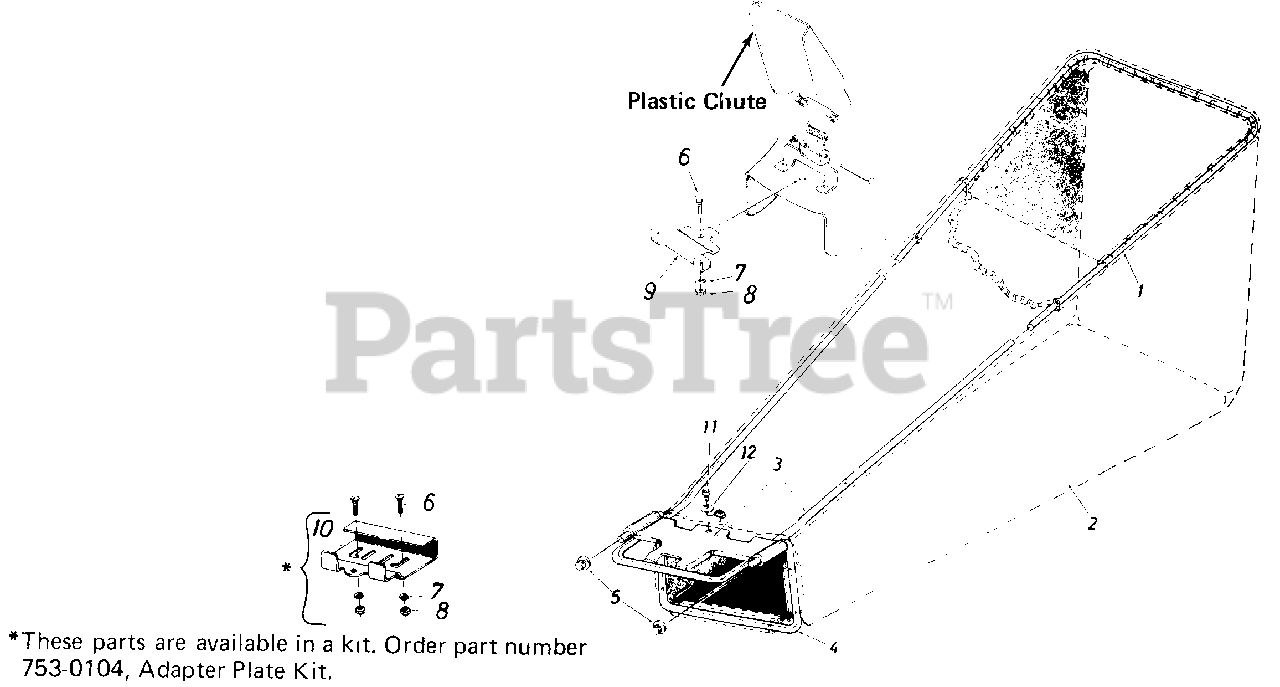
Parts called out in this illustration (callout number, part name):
1	Frame-Upper
2	Grass Catcher Bag
3	Frame-Lower
4	Lower Frame Rod
5	Push Cap
6	Carriage Bolt
7	LockWasher 1/4" I.D.*
8	Hex Nut 1/4-20 Thd.*
9	Adapter Plate
10	Adapter Plate
11	Self-Tap Scr. 1/4 x 1/2" Lg.
12	Bell-Wash. 1/4" I.D.
